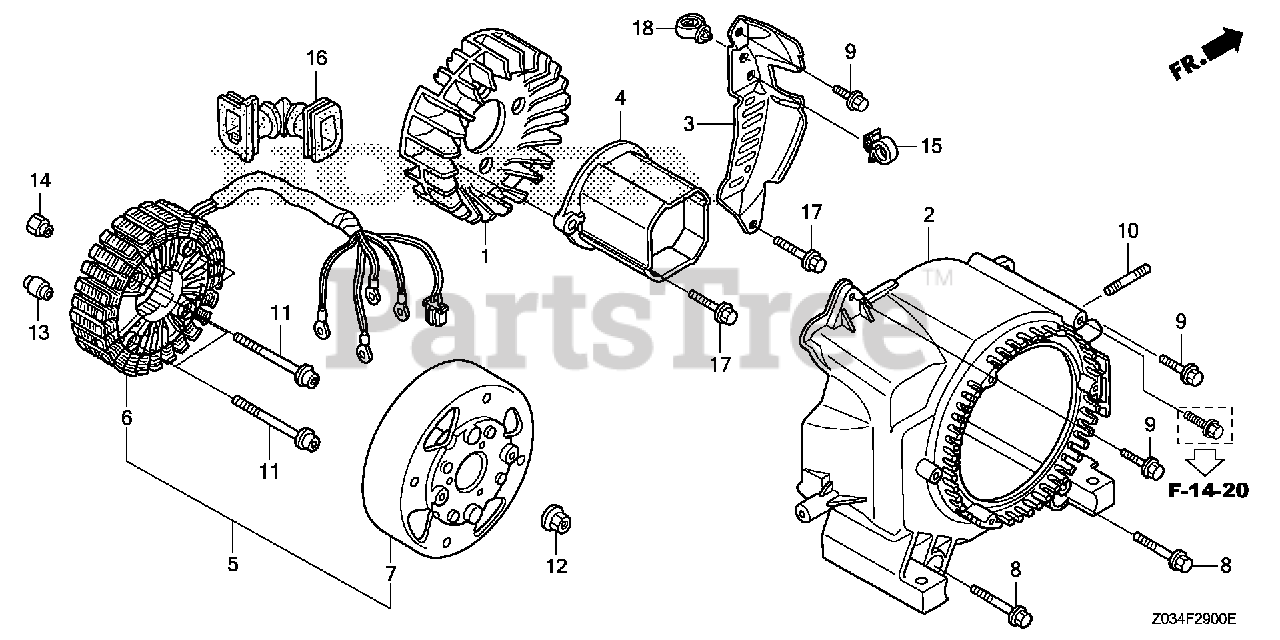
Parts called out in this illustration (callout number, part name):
1	FAN, COOLING
2	COVER, FAN
3	PLATE, SIDE
4	PULLEY, RECOIL STARTER
5	GENERATOR ASSY.
6	STATOR ASSY.
8	BOLT, FLANGE (6X32) (CT200)
9	BOLT, FLANGE (6X20) (CT200)
10	BOLT, STUD (6X25)
11	BOLT, FLANGE SOCKET (6X61) (CT200)
12	NUT, SPECIAL (14MM)
13	COLLAR, STATOR
14	COLLAR, STATOR
15	CLIP, WIRE HARNESS
16	GROMMET, A.C. CORD
17	BOLT, FLANGE (6X20)
